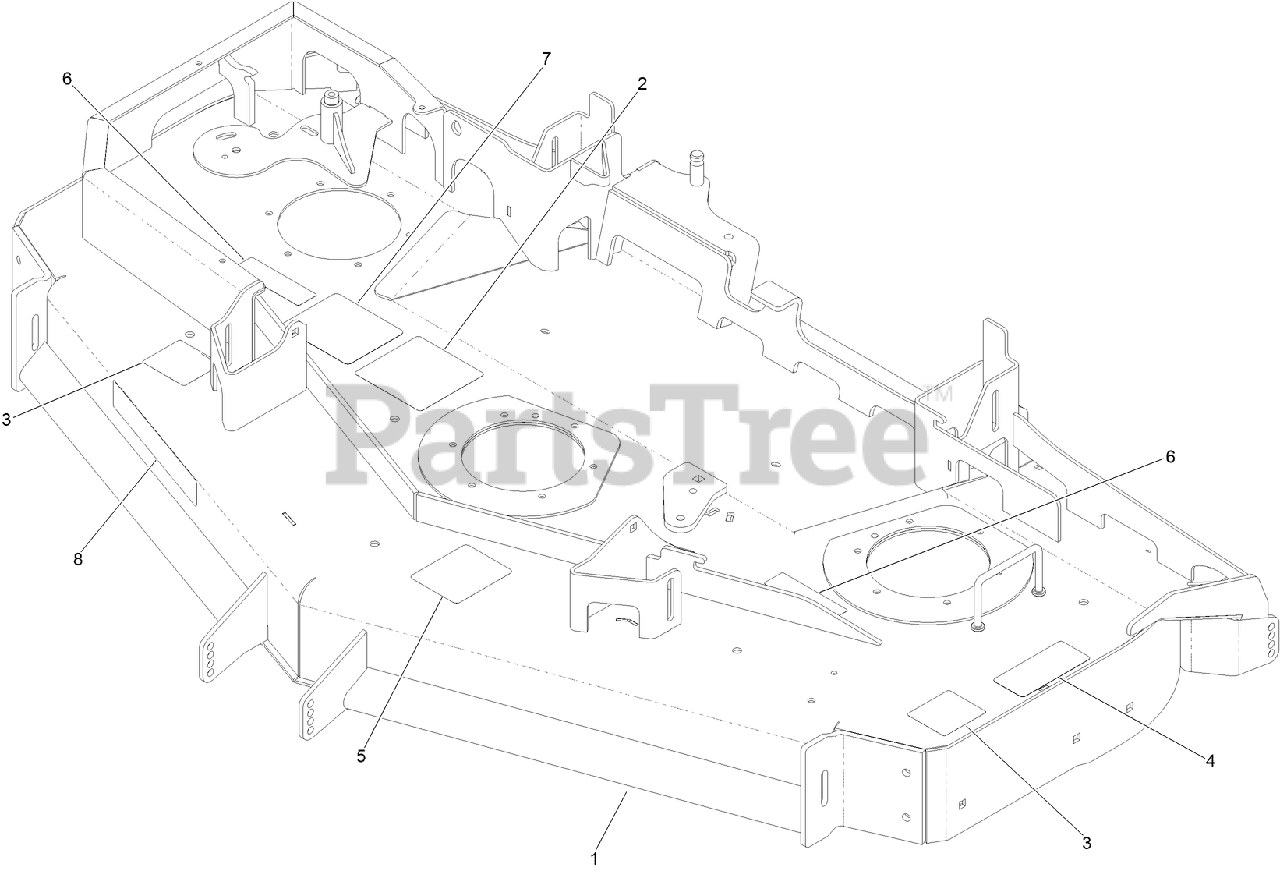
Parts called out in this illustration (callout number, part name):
1	DECK DECAL ASM
2	DECAL-ROUTING, BELT
3	DECAL-DANGER, THROWN OBJECT
4	DECAL-TORQUE, BLADE BOLT
5	DECAL-ROLLER, ANTI-SCALP
6	DECAL-COVER, MISSING
7	DECAL-SPINDLE, COUNTER ROTATING
